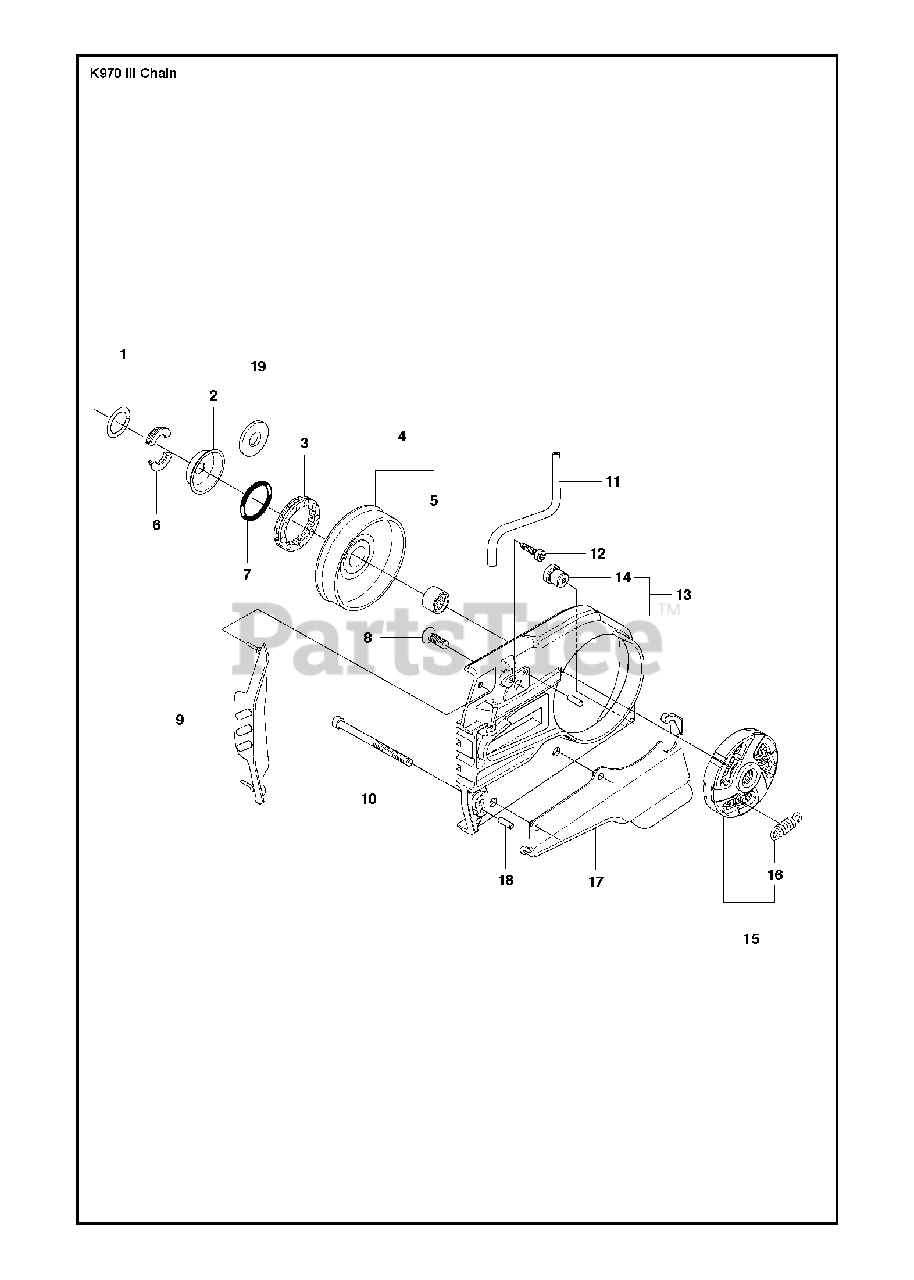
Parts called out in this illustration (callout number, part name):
1	RETAINER RING
2	SUPPORT CUPFor 9-spline and 3/8" only
3	RIM SPROCKETFor 9-spline and 3/8" only
3	RIMFor 7-spline and .444" only
4	GEAR WHEELIncl. 5 For 9-spline and 3/8" only
4	CLUTCH DRUM ASSYIncl. 5 For 7-spline and .444" only
5	NEEDLE BEARING
7	O-RINGFor 9-spline and 3/8"" only
8	SCREW IHCSFM
10	SCREW ITXSCM
12	SCREW ITXSCM
16	CLUTCH SPRING
18	PARALLEL PIN
19	SPACERFor 7-spline and .444" only
